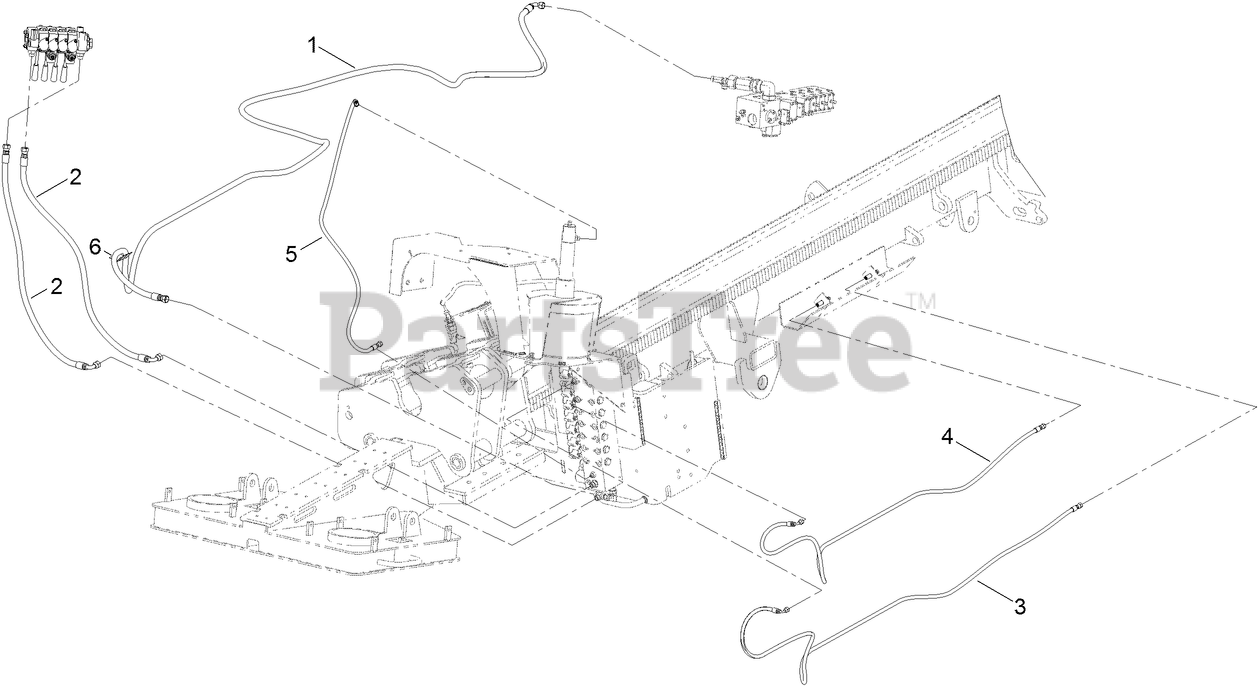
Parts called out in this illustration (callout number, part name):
1	HOSE ASM-HYD
2	HOSE ASM-HYD
3	HOSE ASM-HYD
4	HOSE ASM-HYD
5	HOSE ASM-HYD
6	PROTECTOR-HOSE
